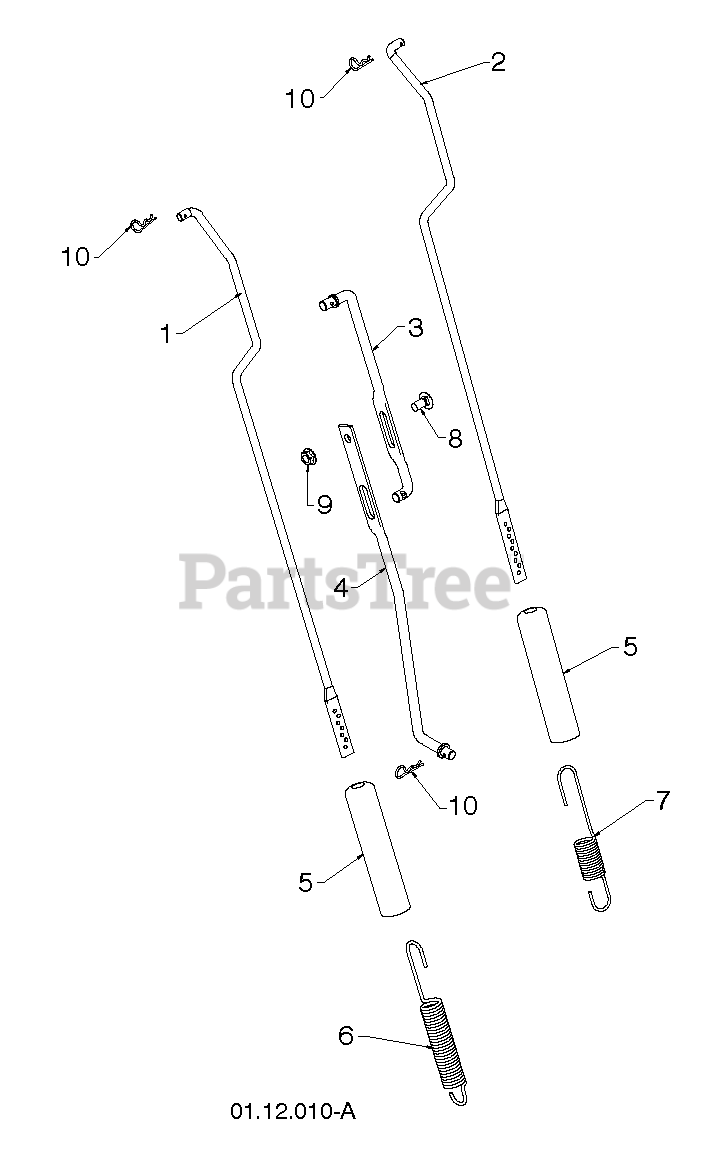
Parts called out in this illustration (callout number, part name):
1	ROD.IMPELLER.CONTROL.SNOW
2	ROD.TRACTION.CONTROL.SNOW
3	ROD, UPPER SPEED CONTROL
4	ROD, LOWER SPEED CONTROL.SNOW
5	SLEEVE, SPRING
6	SPRING.CONTROL.ROD.SNOW
7	SPRING.TRACTION.ROD.SNOW
8	BOLT
9	NUT.FLANGE.5/16
10	SPRING RETAINER
